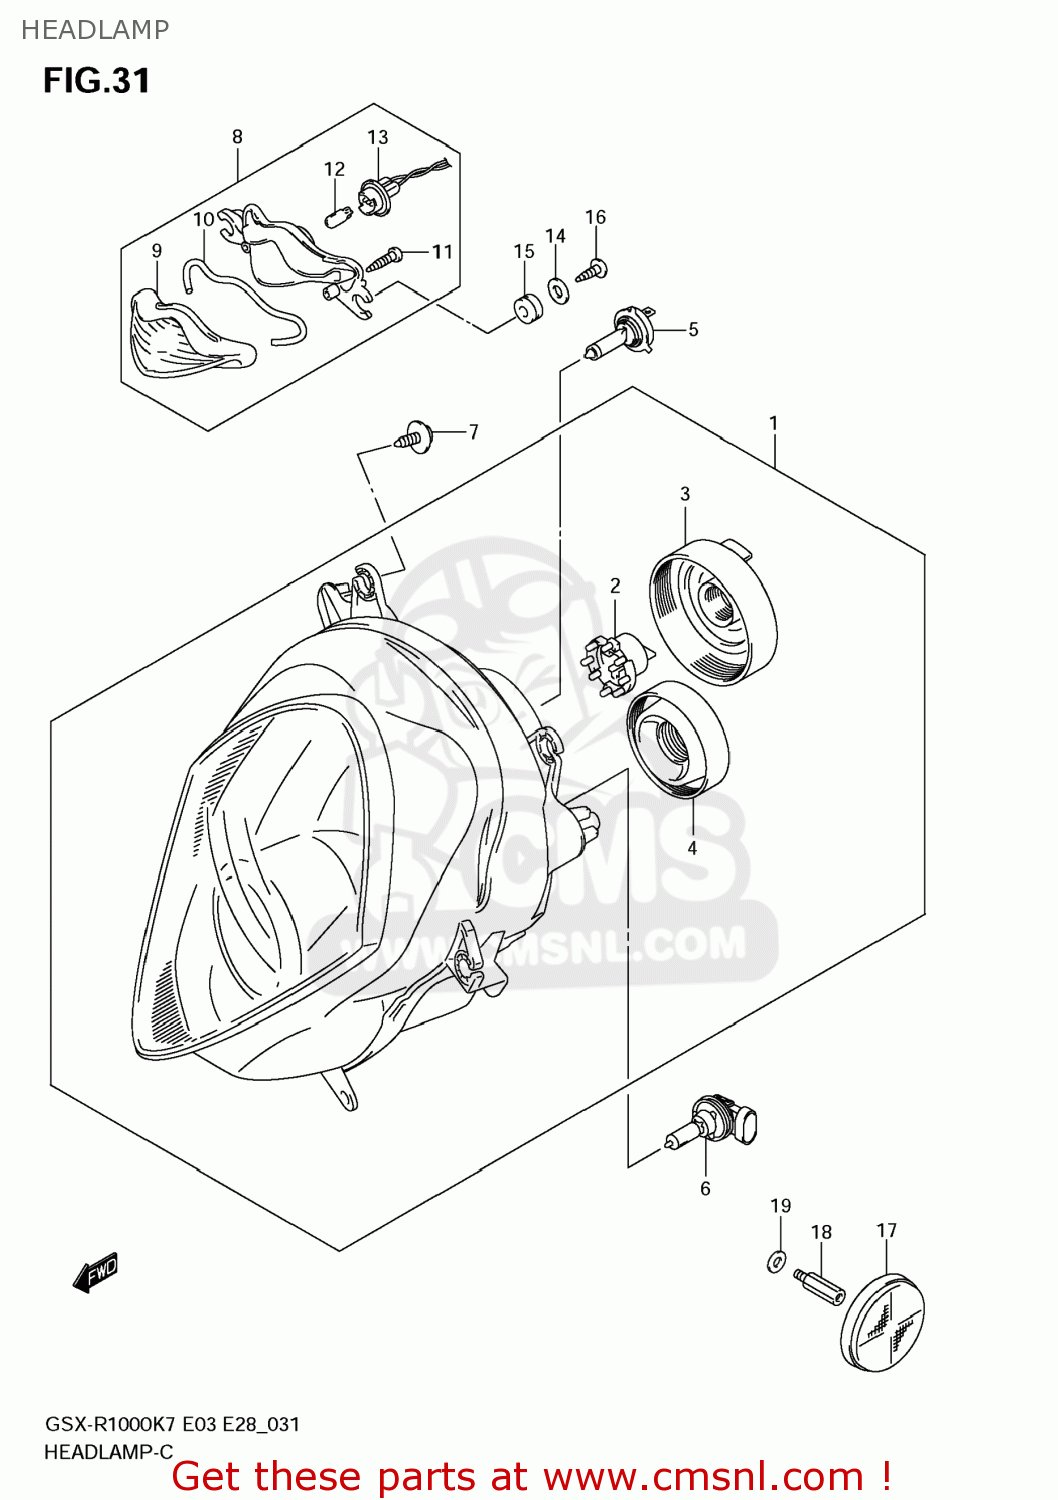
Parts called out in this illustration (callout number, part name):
1	HEADLAMP ASSY
2	ADAPTER ASSY
3	COVER,SOCKET
4	COVER,SOCKET
5	BULB(12V55W/H7/PX26D/PHILIPS)
6	BULB(12V65W,H9)
7	SCREW(5X15)
8	LAMP ASSY,FR POSITION
9	LENS
10	GASKET (NAS)
11	SCREW
12	BULB(12V5W)
13	SOCKET,CORD
14	WASHER(5.5X18X1)
15	CUSHION
16	SCREW
17	REFLECTOR,REFLEX
18	BOLT
19	WASHER(8.5X14X1.6)
